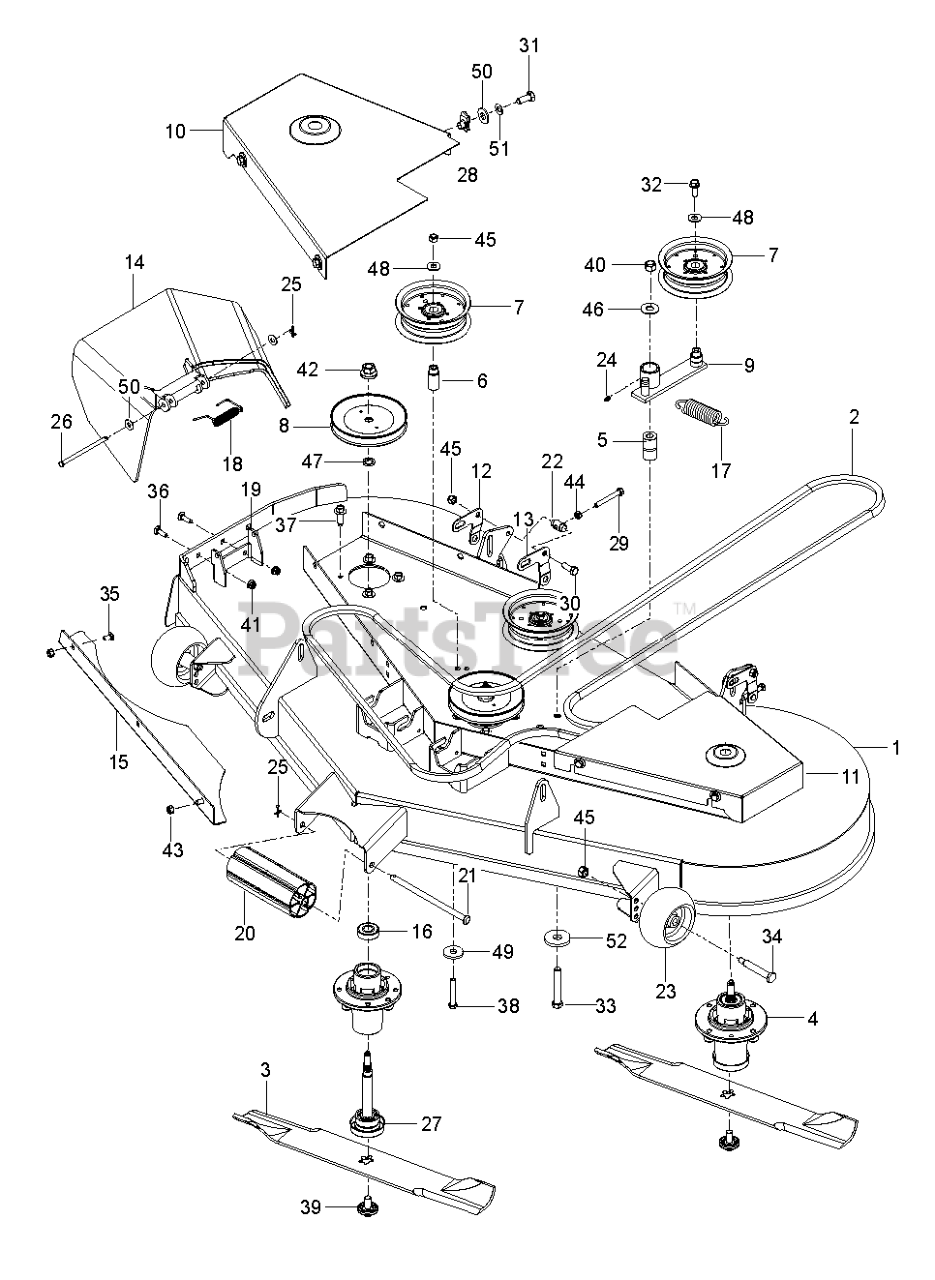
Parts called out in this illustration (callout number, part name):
1	DECK SVC MZT 61 W/DECALS ORG
2	BELT, DECK
3	BLADE, 21"
4	MANDREL ASM, CAST IRON
5	PIVOT BUSHING
10	BELT SHIELD, RH ORANGE
11	BELT.SHIELD.LH.ORANGE
12	BRACKET.RT.PNT.MS431
13	BRACKET.LH.PNT.MS431
14	DISCHARGE CHUTE 61"
15	CONFINEMENT PLATE 61
19	BRACKET MZ CHUTE
20	NOSE ROLLER 48"
23	WHEEL GAGE DONUT
24	GSPW Zerks
26	Pins
28	U-CLIP 5/16-18 NUT RETAINER
31	SCREW HEXAGON HEAD SCREW 5/16-
34	BOLT SHOULDER 3/8-16X3.38
35	BOLT ROUND HEAD SQUARE NECK BO
37	BOLT.HEX.WASHR.HED.313-18X1.19
39	BOLT.WASHER.ASM.7/16-2
41	NUT HEXAGON FLANGE 5/16-18 ST
47	WASHER.SPACER.MANDREL
48	GSPW Washers
